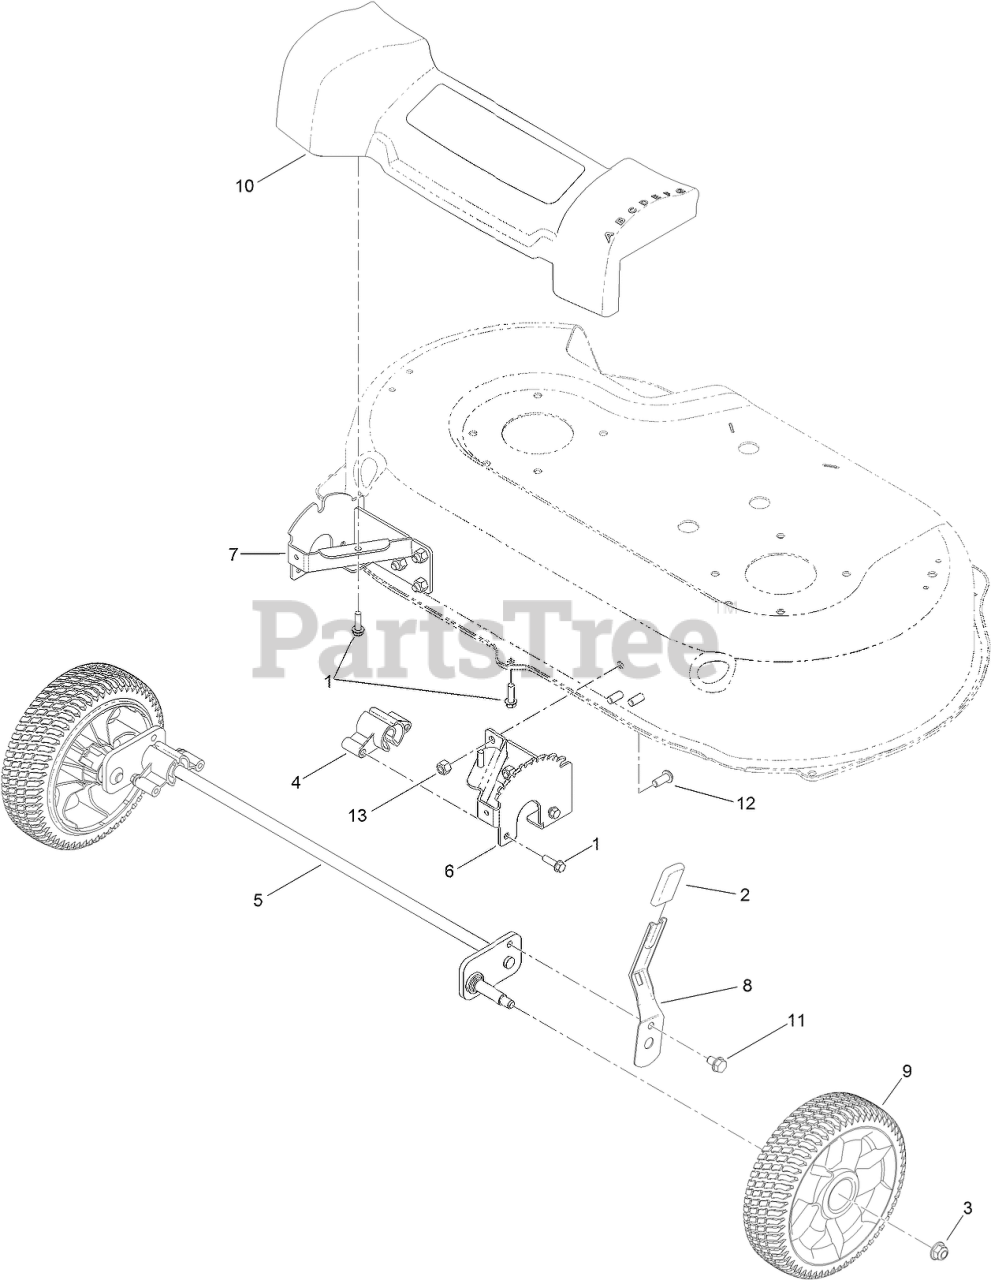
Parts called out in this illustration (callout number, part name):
1	SCREW-HWH
2	GRIP-LEVER
3	NUT-HF, NI
4	BUSHING-PIVOT, FRONT
5	AXLE-FRONT
6	PLATE-HOC, LH
7	PLATE-HOC, RH
8	ARM-SPRING
9	8 Inch Wheel ASM
10	FRONT COVER ASM
11	SCREW-HWH
12	SCREW-HSBH
13	NUT-LOCK, NI
